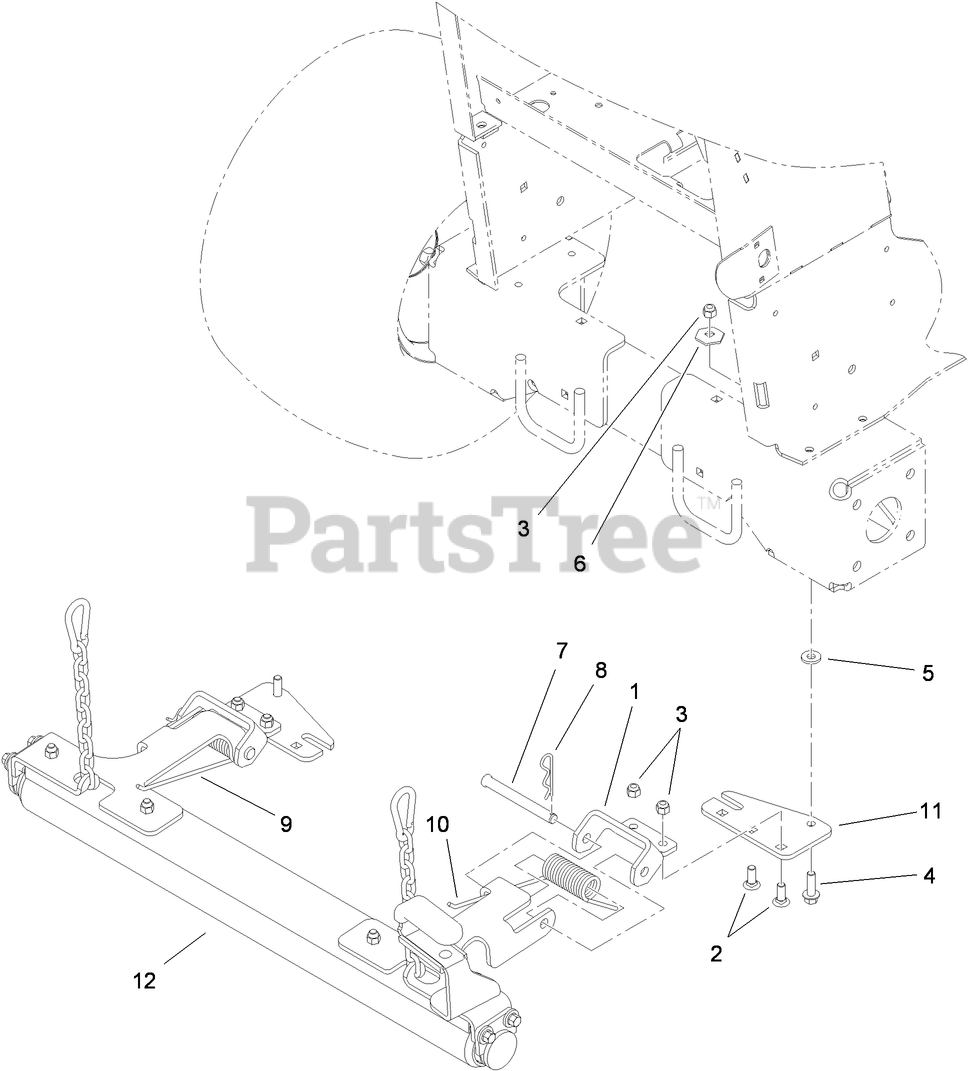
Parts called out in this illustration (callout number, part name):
1	BRACKET-MOUNT, STRIPER
2	SCREW-CARR
3	NUT-LOCK, NI
4	SCREW-HHF
5	WASHER-SPACER
6	LOCKWASHER-PYRAMID
7	PIN-CLEVIS
8	PIN-HAIR
9	SPRING-TORSION
10	SPRING-TORSION
11	PLATE-HINGE
12	ROLLER ASM
